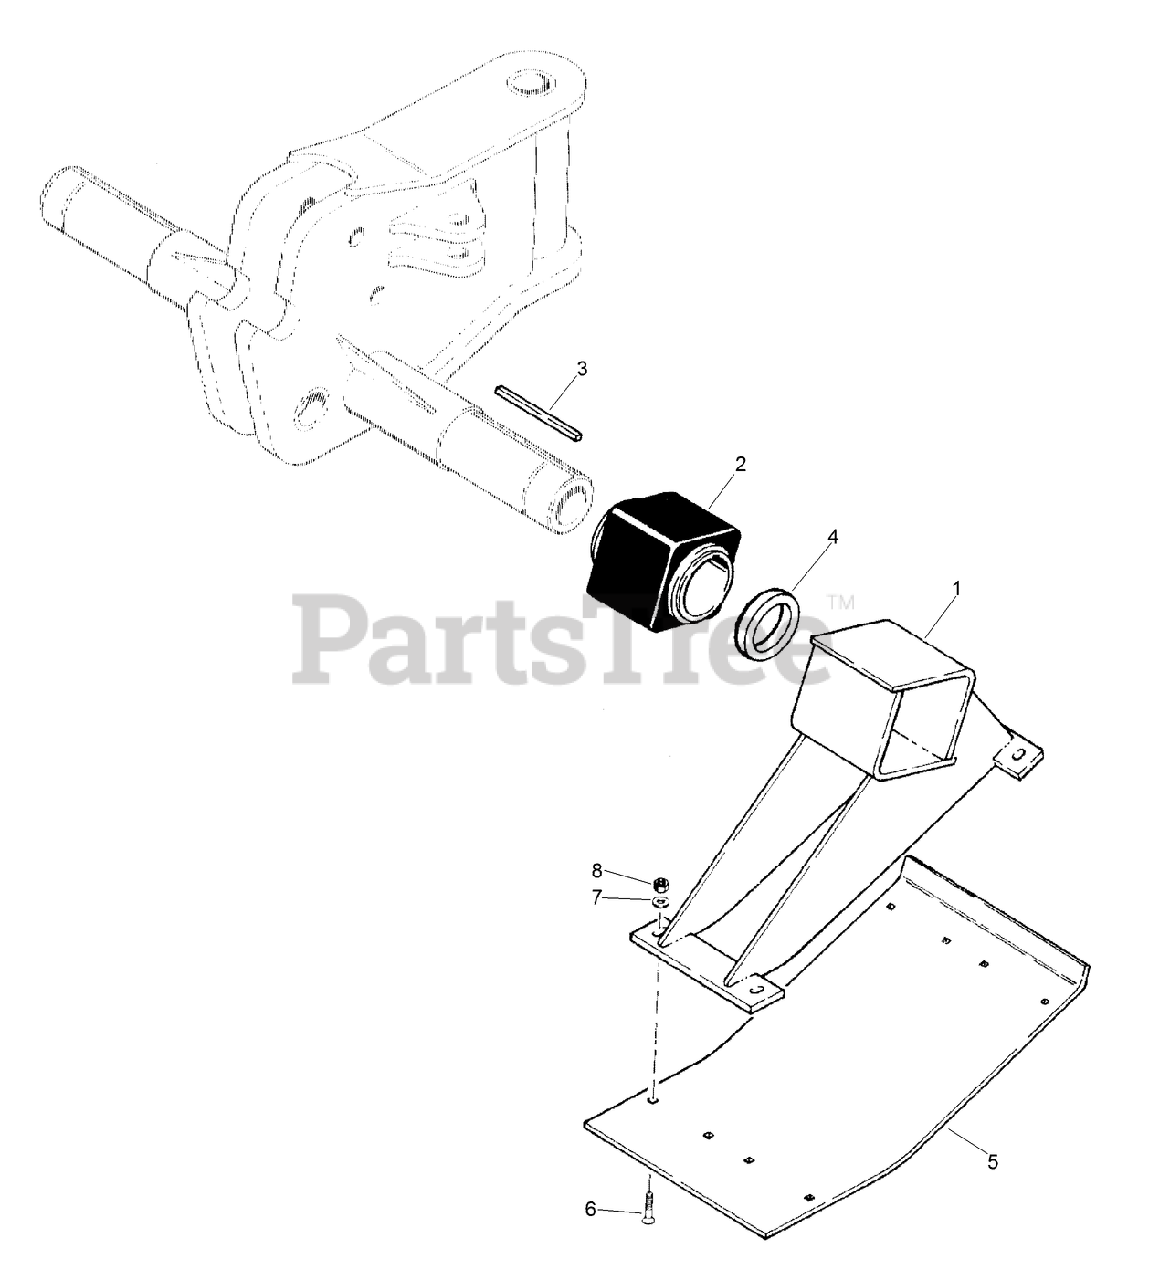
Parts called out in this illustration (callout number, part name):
1	SHOE-PLOW
2	JOINT-CENTER, BONDED RUBBER
4	RING-external retaining, No. 300, rear plow pivot pin retaining
5	PLATE-skid shoe, 12 inch wide
6	SCREW-PLOW
7	WASHER-FLAT
8	NUT-HEX
